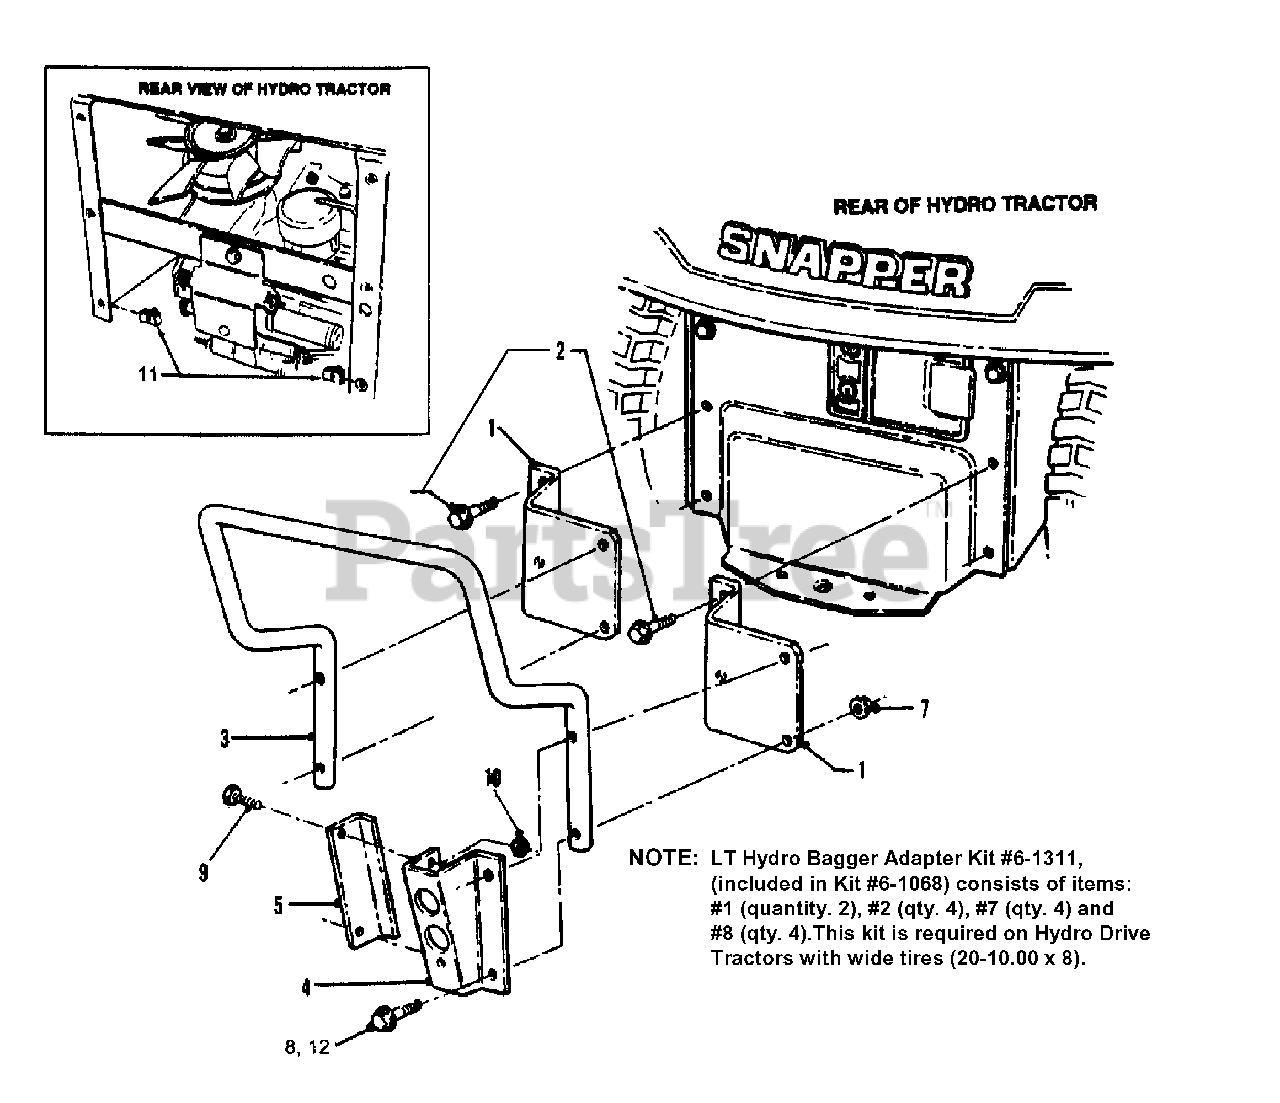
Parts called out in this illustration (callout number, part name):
1	BRACKET, Bagger Adapter
2	BOLT, 5/16-18 x 1" Hex Flange Lock, Grade 5
3	BUMPER
4	BRACKET, Support
5	BRACKET, Stand-off
7	NUT, 5/16-18 Hex Flange Lock, Grade 5
8	BOLT, 5/16-18 x 1-1/2" Hex Flange Lock, Grade 5 (2 in bag; 4 in kit)
9	SCREW, 1/4-20 x 5/8" Hex Head Cap, Grade 5
10	NUT, 1/4-20 Hex Flange Lock, Grade 5
11	NUT, 5/16" Push-on
12	BOLT, 5/16-18 x 1-3/4" Hex Flange Lock, Grade 5
